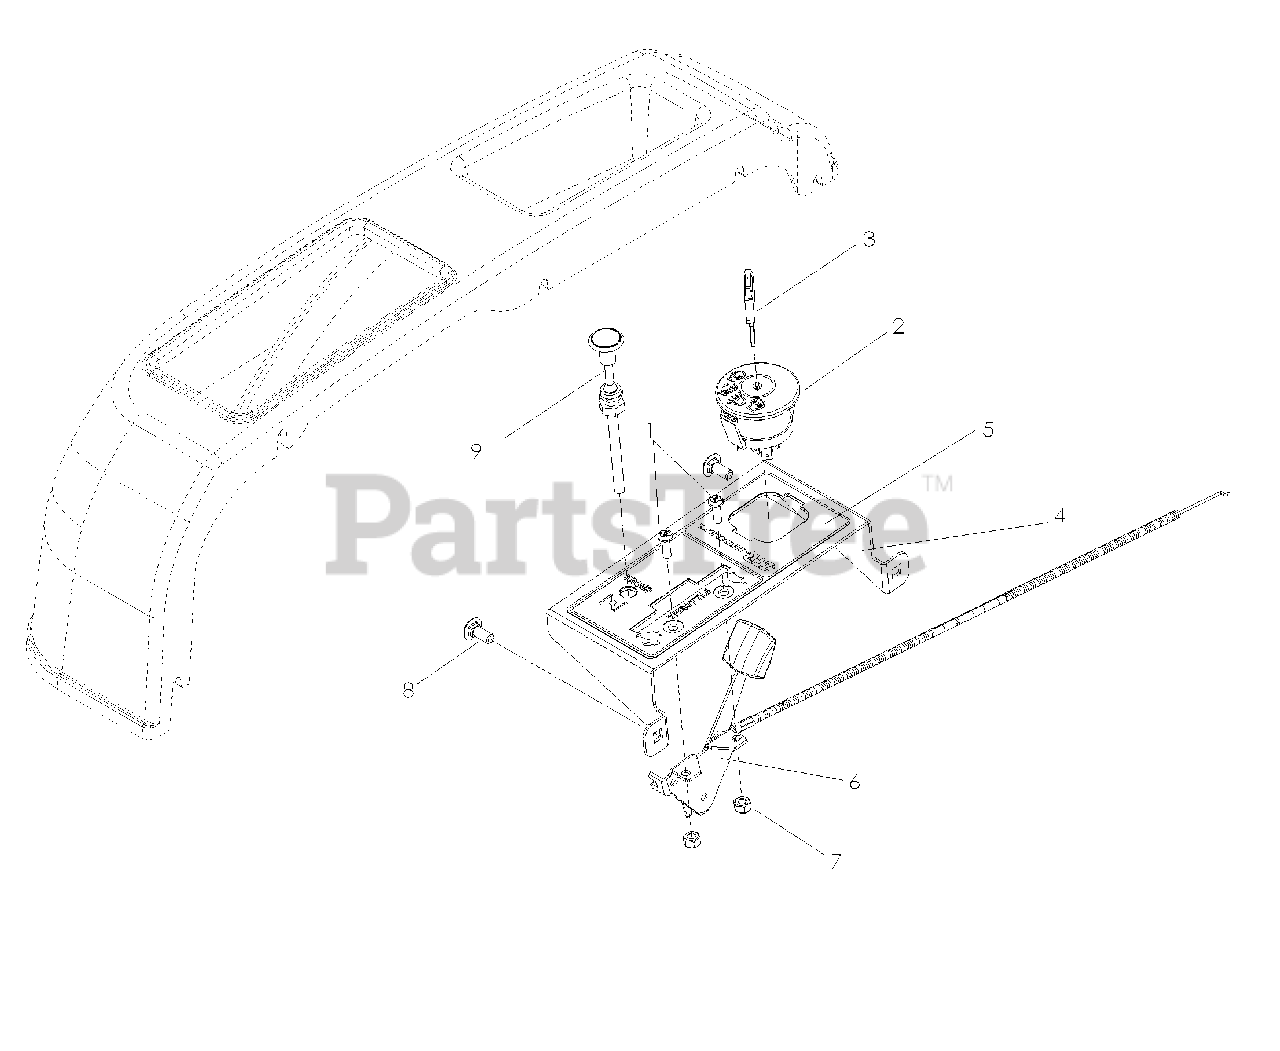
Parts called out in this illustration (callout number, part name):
1	SCREW #10-24 X 5/8
2	IGNITION SWITCH
3	KEY
4	PANEL, CONTROL, PAINTED
5	DECAL, CONTROL PANEL
6	THROTTLE CABLE
7	NUT 10-24 NYLOC
8	RHSSNB, 1/4-20X5/8
9	PUSH/PULL CHOKE CABLE
